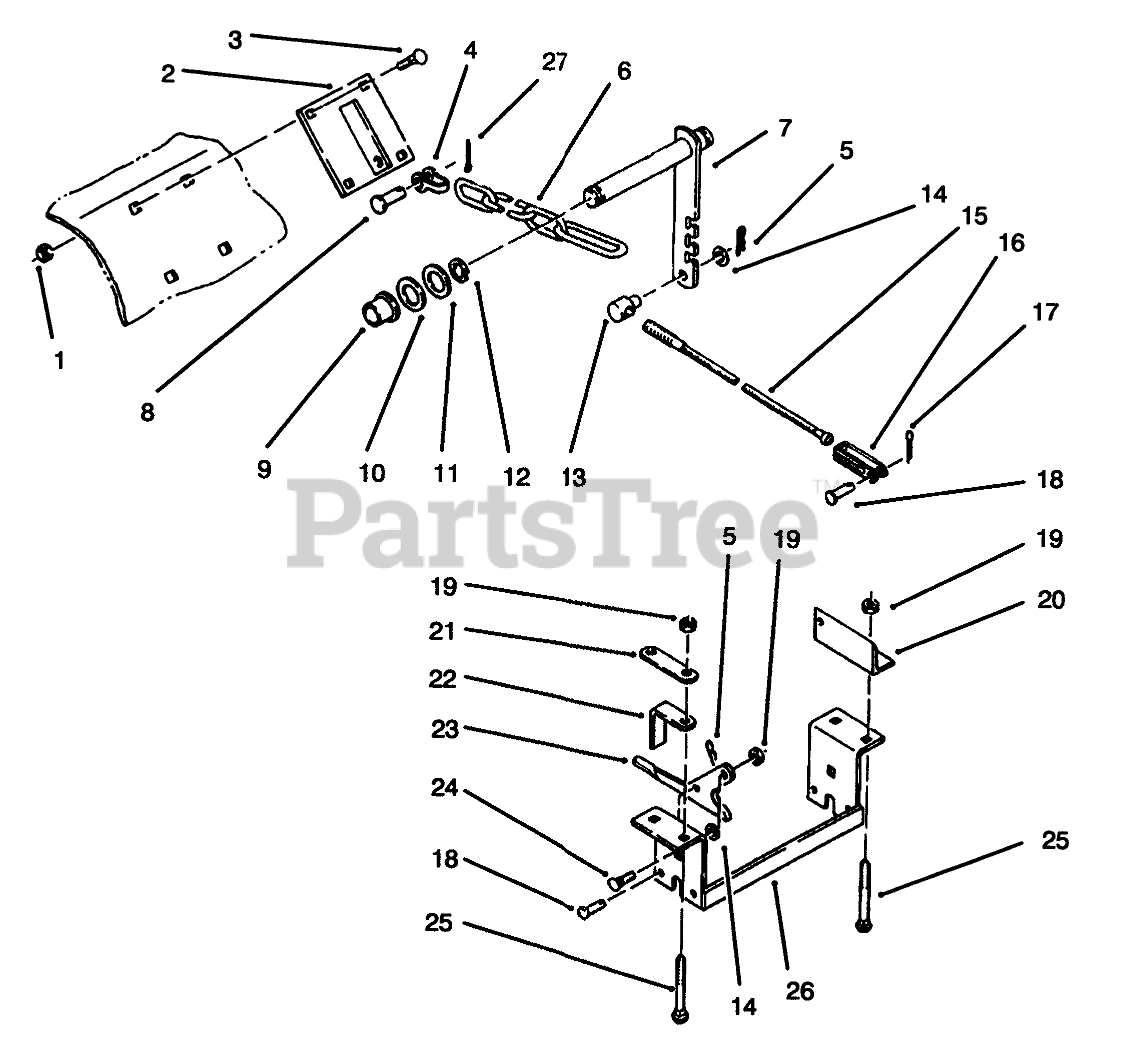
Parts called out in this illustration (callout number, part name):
1	NUT-LOCK, NI
2	HITCH ASM
3	BOLT-CARR
4	CLEVIS ASM
5	Hairpin-Cotter (Incl. Ref. #8 & 27)
6	CHAIN LIFT
7	ASSY LEVER R
8	Clevis Pin
9	BUSHING-BRONZE
10	WASHER
11	WASHER-SHIM
12	E-RING
13	TRUNNION-CLUTCH ROD
14	WASHER-FLAT
15	CABLE
16	CLEVIS-SHORT
17	PIN-COTTER
18	Pin
19	NUT-HEX
20	LINK-BRACKET R
21	BRACKET-REAR LINK MOUNTING
22	SPACER-BRACKET
23	PLATE-LATCHING
24	BOLT-CARR
25	SCREW-CARR
26	Bracket
27	PIN-COTTER
